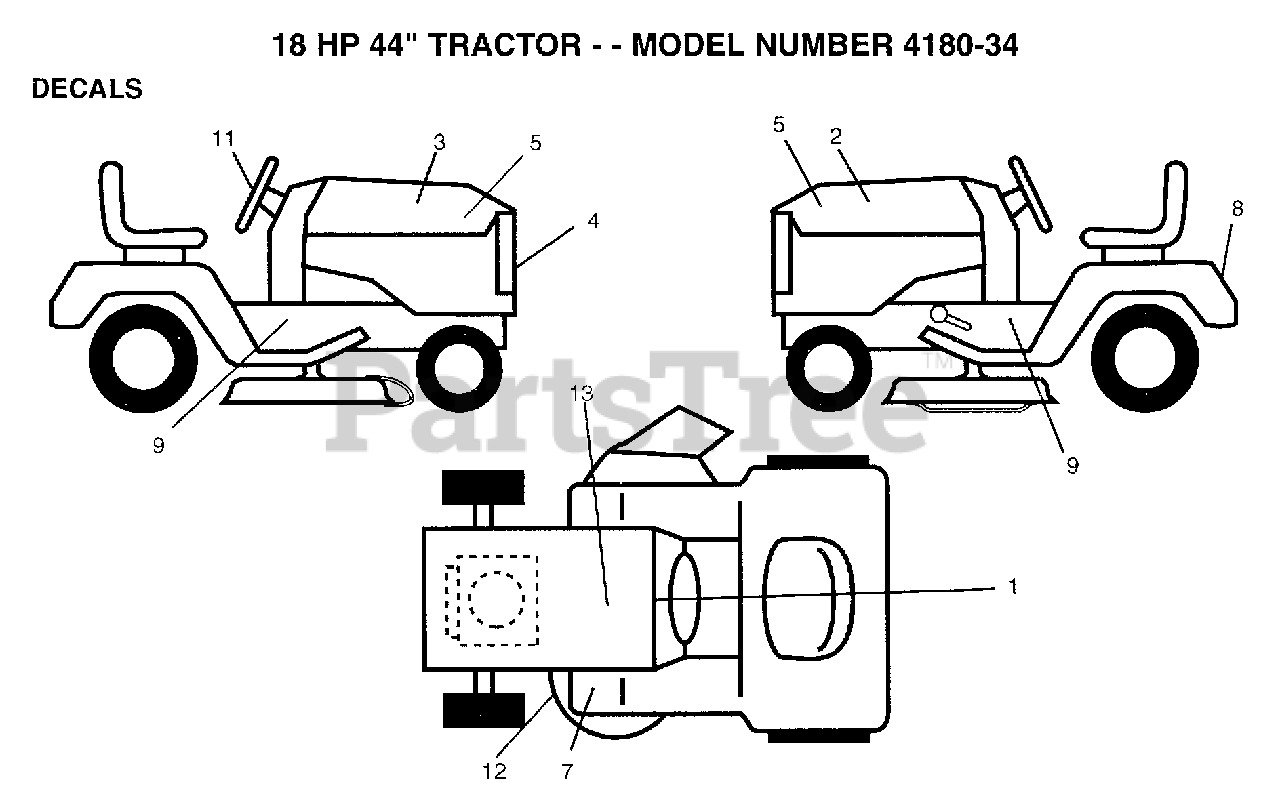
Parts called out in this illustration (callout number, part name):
2	HOOD DECAL LH
4	GRILL DECAL
5	NAMEPLATE LOGO
8	REFLECTOR-TAIL YT
13	DECAL
